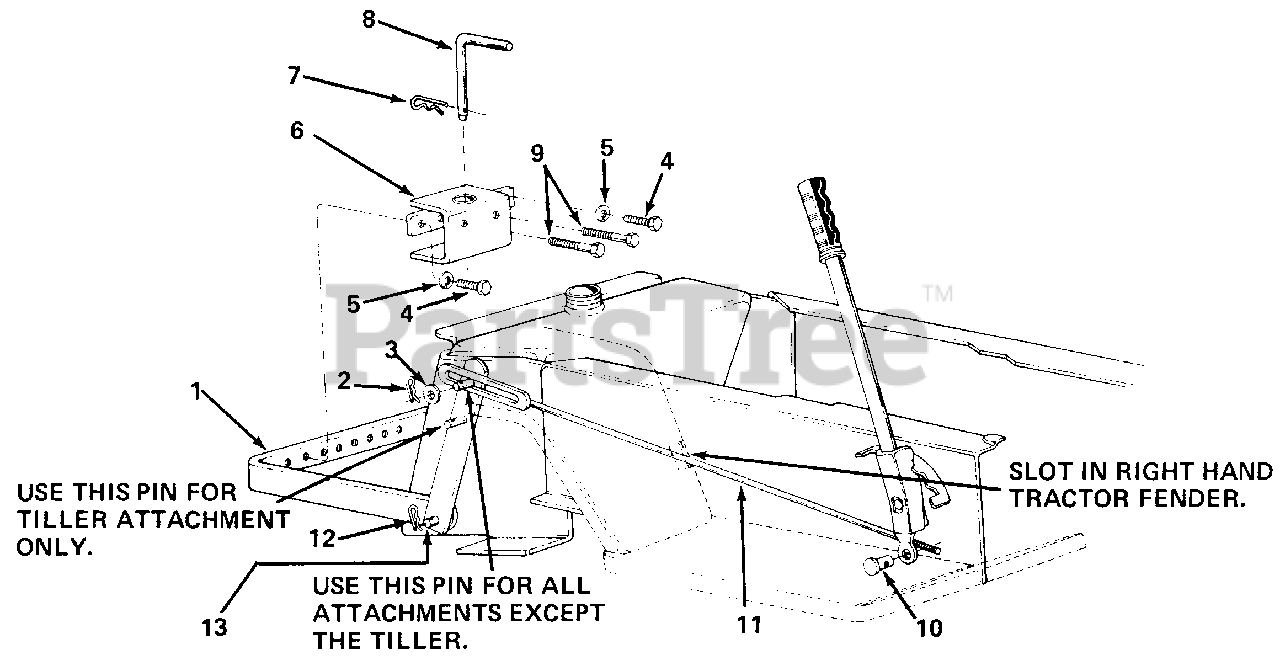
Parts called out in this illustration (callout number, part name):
3	Fl.-Wash. 1/2" I.D.
4	Hex Scr. 1/2-13 x 1.00" Lg.*
5	L.-Wash. 1/2" Scr.*
9	Hex Scr. 1/2-13 x 3.00" Lg. *
10	Adjustment Ferrule
